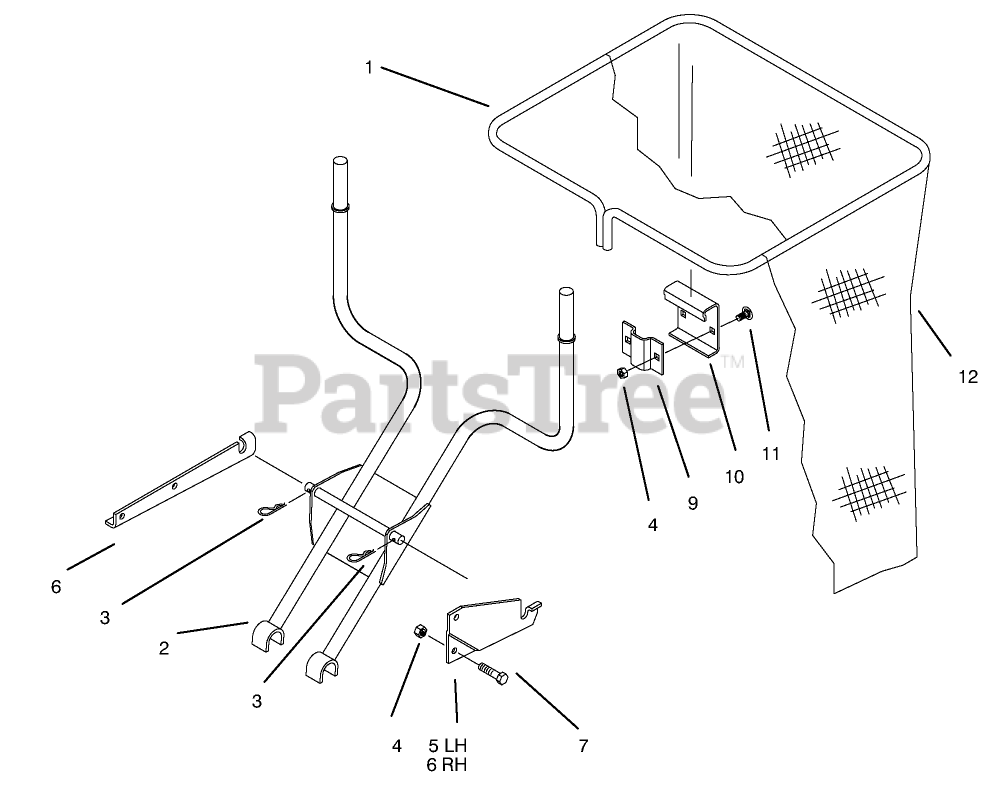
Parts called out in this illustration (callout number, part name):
3	PIN-COTTER, HAIR
4	NUT-LOCK, NI
7	SCREW-HH
11	BOLT-CARR
12	BAG-DEPTH
